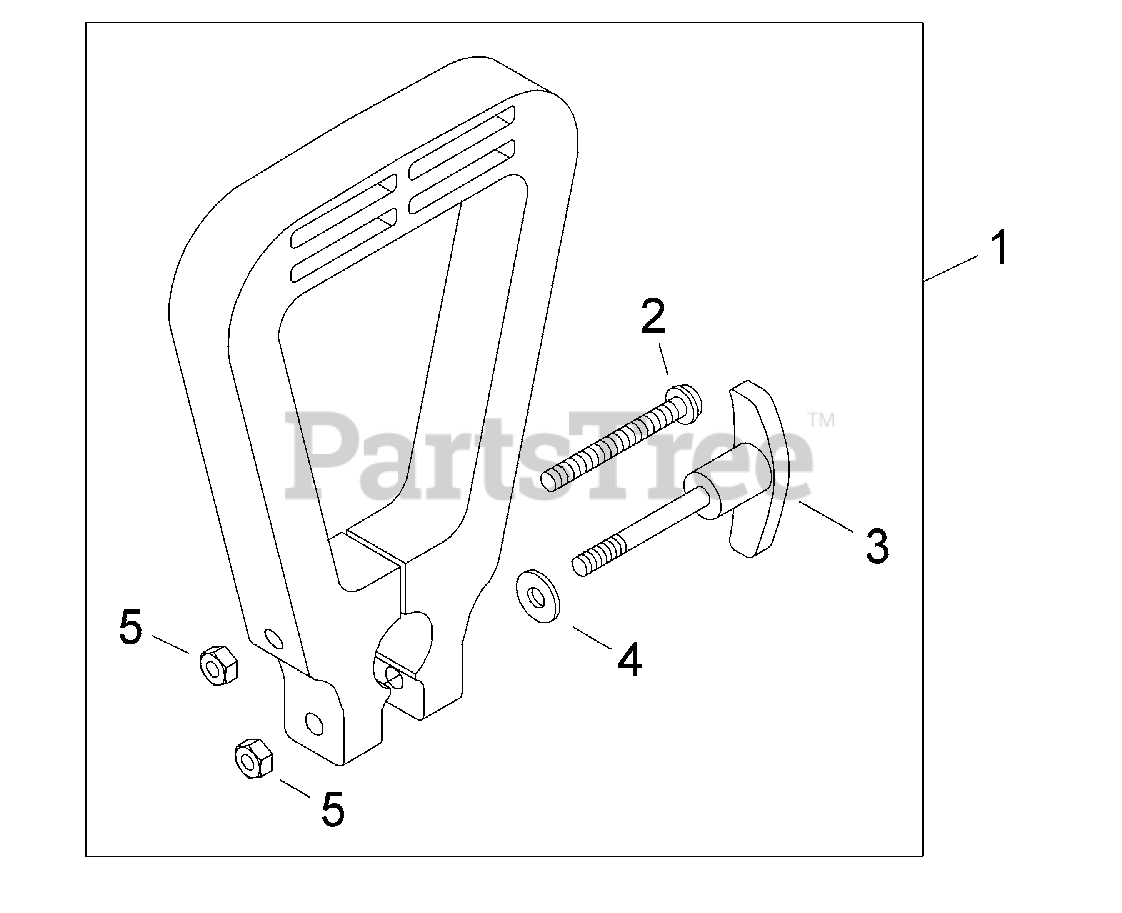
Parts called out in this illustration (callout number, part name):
1	HANDLE ASSY
2	SCREW 6
3	KNOB, SCREW
4	WASHER 6
5	NUT, HEX M6
